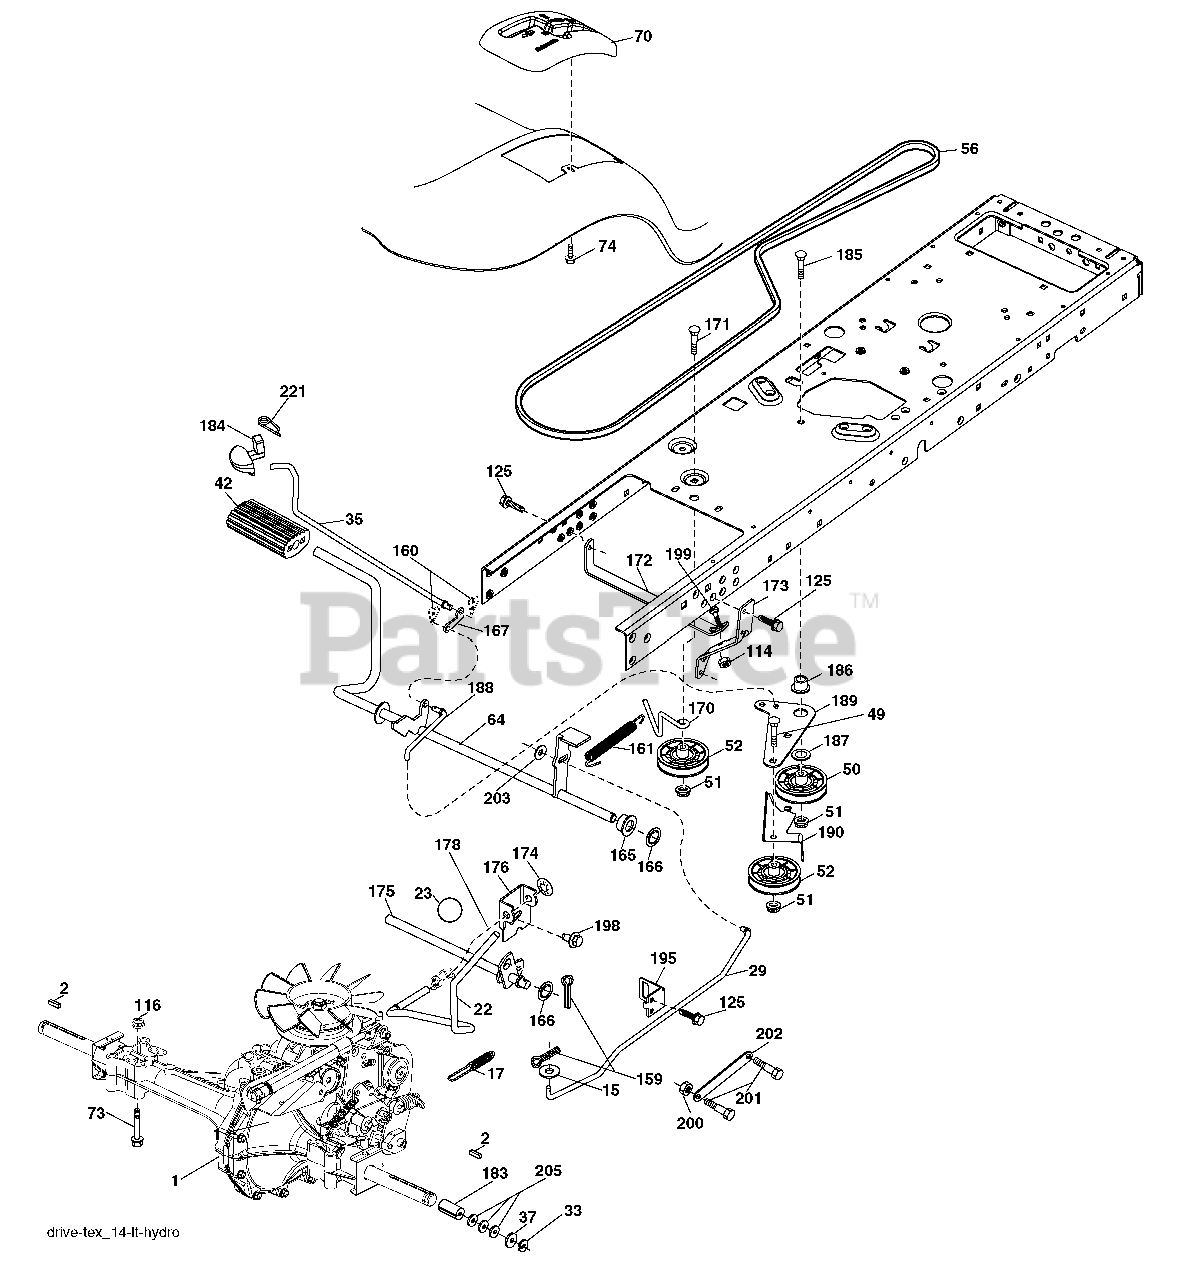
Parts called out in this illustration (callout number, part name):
2	Key
15	Washer 13/32 x 13/16 x 16 Ga.
17	Spring, Brake
22	Rod Shift
23	Knob
29	Rod, Brake
33	Ring E
35	Rod, Brake, Park
37	Washer 25/32 x 1-1/4 x 16 Ga.
42	Cover, Foot Pedal
49	Bolt
50	Pulley Idler Flat
51	Lock Nut 3/8-16
52	Idler V-Groove 910" Offset
56	V-Belt, Drive
64	Shaft Asm. Pedal Brake Control
70	Console Shift
73	Bolt Hex Flghd 5/16-18 Gr. 5
74	Screw Hexwsh Hi-Lo 1/4 x 1/2 unc
114	Nut Lock Hex W/INS 5/16-18 unc
116	Nut Lock Hex Flange 5/16-18
125	Screw 5/16-18 x 3/4
159	Pin Cotter 1/8 x 3/4
160	Retainer Clip
161	Spring, Return, Clutch
165	Bushing
166	Nut Push .625
167	Latch Brake Parking
170	Keeper Belt Centerspan
171	Bolt
172	Strap Torque LH
173	Strap Torque RH
174	Nut Push
175	Shaft Asm
176	Asm Clevis Rod Shift
178	Spring Shift
183	Spacer Axle
184	Handle Parking Brake
185	Bolt
186	Spacer Retainer
187	Washer
188	Link Clutch Ground Drive
189	Bellcrank Ground Drive
190	Keeper Bellcrank Ground Drive
195	Bracket Rod Brake
198	Screw 7/16-147 x 7/8 fl ange head
199	Bolt RDHD SQNK 5/16-18 unc x 1
200	Nut Center Lock 5/16-18 unc
201	Bolt Shoulder 5/16-18 unc
202	Link Trans
203	Washer 11/32 x 11/16 x 16 Ga.
205	Washer 25/32 x 1-5/8 x 16 Ga.
221	Retainer Spring Clip Handle
